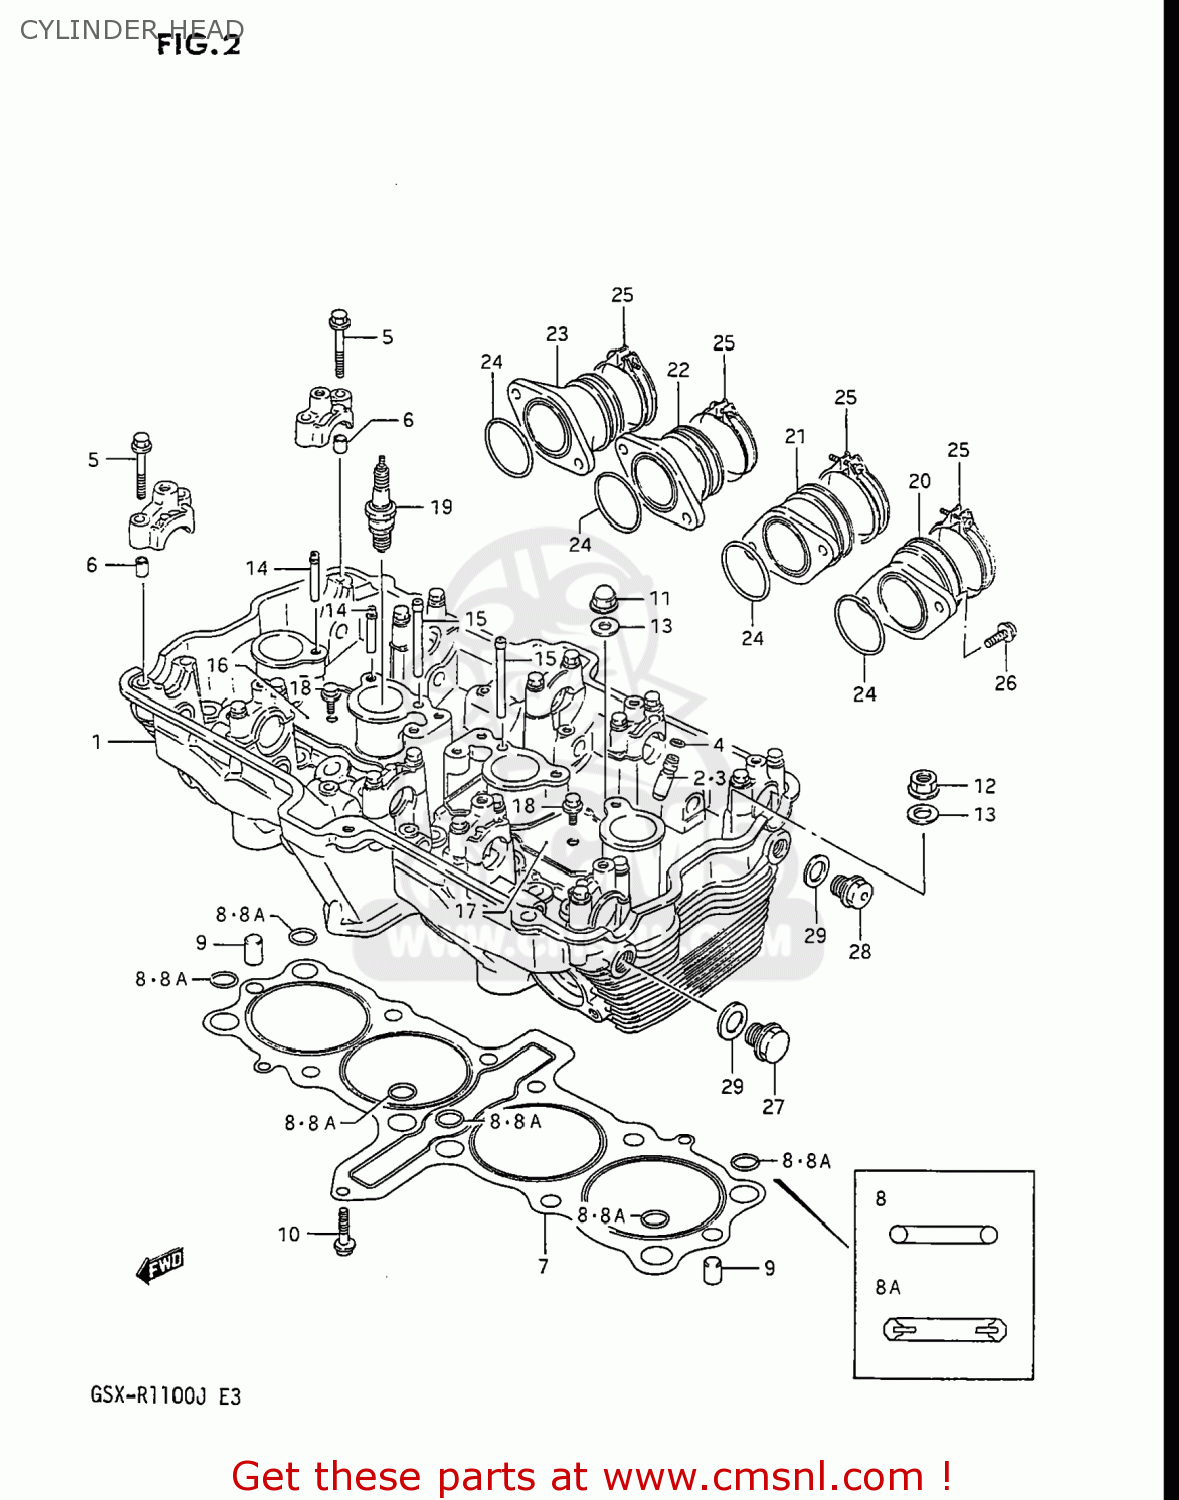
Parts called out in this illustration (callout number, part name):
1	HEAD ASSEMBLY,CYLINDER
2	GUIDE,VALVE
3	GUIDE,VALVE
4	RING,SNAP
5	BOLT(6X39)
6	PIN(6.2X8X11)
7	GASKET,CYLINDER HEAD (NAS)
8	O RING,HEAD GASKET
8A	O RING,HEAD GASKET
9	PIN
10	BOLT
11	NUT
12	NUT
13	GASKET(10.2X20X2).3 (NAS)
14	PIPE,OIL NO.1
15	PIPE,OIL NO.3
16	PLATE,OIL PIPE,R
17	PLATE,OIL PIPE,L
18	BOLT
19	SPARK PLUG
20	PIPE,INTAKE
21	PIPE,INTAKE
22	NET,INTAKE
23	PIPE,INTAKE
24	O RING(D:2.4,ID:39.7)
25	CLAMP
26	SCREW
27	PLUG
28	PLUG
29	GASKET(14X19.2X2) (NAS)
